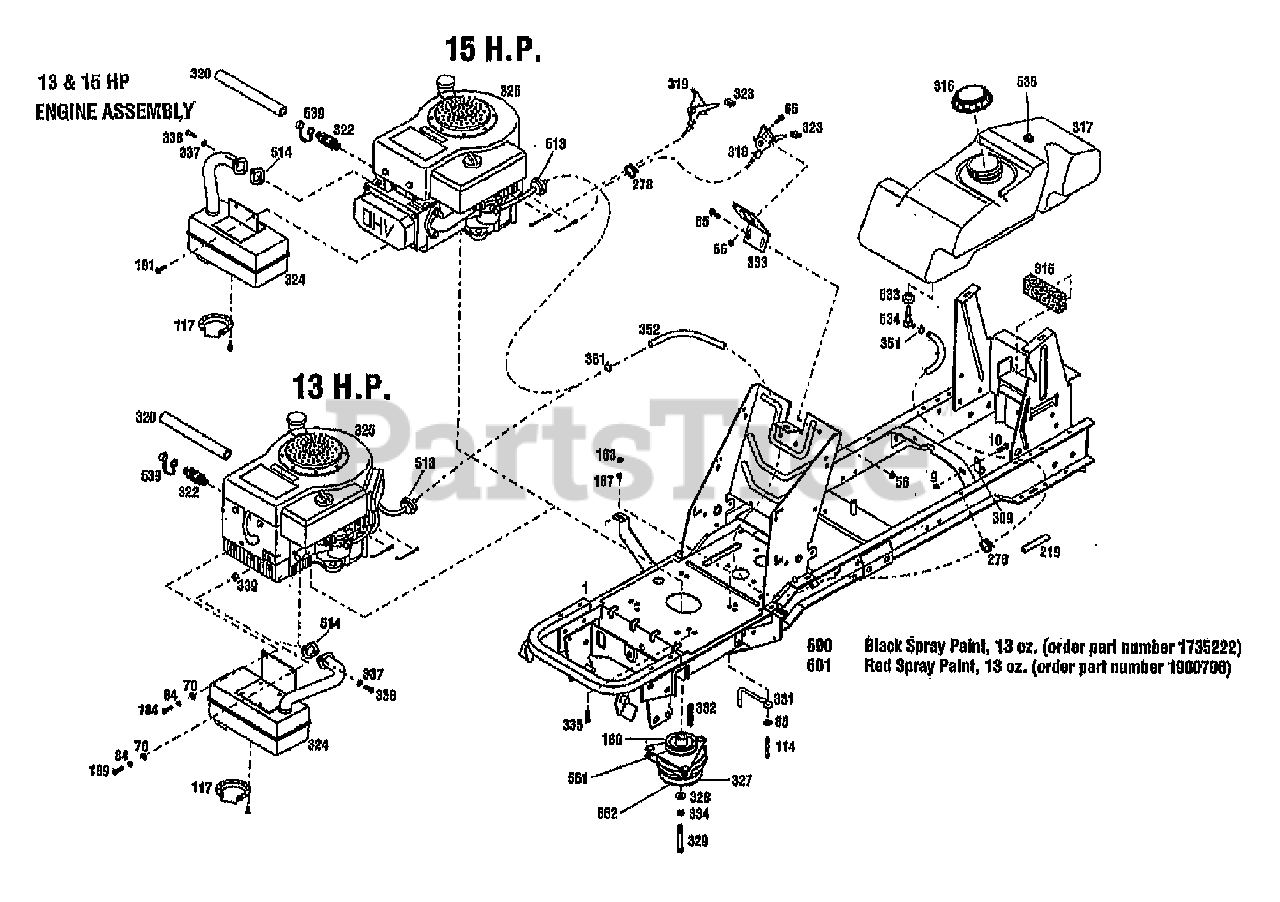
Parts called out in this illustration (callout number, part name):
1	ASSM-FRAME LTX
9	NUT-HFLK 5/16-18 ZP
10	SCR-HHC 5/16-18X.75 GR 5 ZP
56	NUT-HF/LK 1/4-20 ZP
65	SCR-HH 1/4-20X.625
70	WASHER-FLAT 1/4 SAE
84	WASHER-LK .25 ZP
114	SCR-THRD FRM 3/8-16X1.50
117	DEFLECTOR-MUFFLER
163	NUT-HEX 3/8-16 ZP
167	WASHER-LK .375 @ DEPL
184	SCR-HH 1/4-20 X .875
189	SCR-HH 1/4-20X1.25
278	TIE-CABLE NYLON BLACK
309	CLIP-J
316	CAP-FUEL
317	TANK-FUEL
318	CONTROL-THROTTLE
319	CONTROL-CHOKE
320	HOSE-OIL DRAIN
322	ASSM-OIL VALVE
324	MUFFLER
325	ENGINE, 13HP BRIGGS & STRATTON, MODEL 28M707
325	ENGINE, 15HP BRIGGS & STRATTON, MODEL 28N707
327	CLUTCH-ELECTRIC
328	WASHER-SPEC 1.42X.468X.25 ZP
331	CLUTCH-RETAINER
332	KEY-.25 SQ X 2.5
334	WASHER-LK .438 ZP
335	SCR-HH 3/8-16X1.0 THDFM
337	WASHER-LOCK
338	SCR-HXSKT 5/16-18X.75 BO
339	SPACER-.625X.344X.34
351	CLAMP-HOSE
352	LINE-FUEL
513	FILTER-FUEL
514	MUFFLER GASKET
539	CAP-OIL DRAIN
600	PAINT-BLACK SPRAY
601	PAINT-RED SPRAYCAN POWDER
